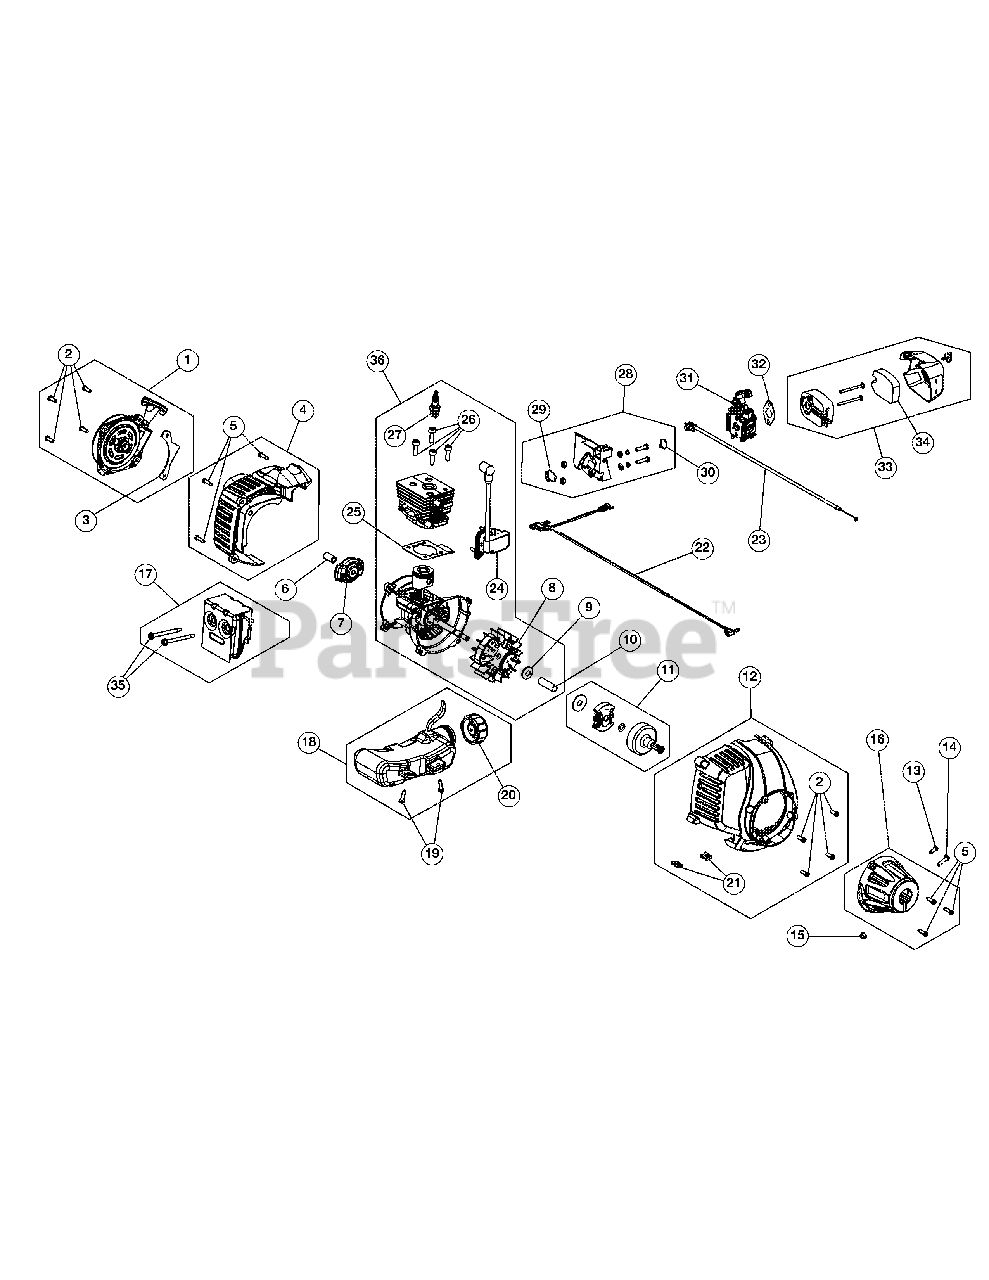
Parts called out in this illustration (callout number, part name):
1	Rear Cover Assembly (Incl. 2 & 3)
2	Starter Screw
3	Starter Assembly Guard (Incl. 2)
4	Rear Engine Cover Assembly (Incl. 5)
5	Cover Screw
6	Adapter
7	Pawl Assembly
8	Flywheel Assembly
9	Washer
10	Spacer
11	Clutch Assembly
12	Front Engine Cover Assembly (Incl. 2 & 21)
13	Anti-Rotation Screw
14	Clamp Screw
15	Clamp Nut
16	Clutch Cover Assembly (Incl. 5)
17	Muffler Assembly (Incl. 35)
18	Fuel Tank Assembly (Incl. 19 & 20)
19	Tank Screw
20	Fuel Cap
21	U-Shaped Nut
22	Lead Wires
23	Throttle Cable
24	Module Assembly
25	Cylinder Gasket
26	Cylinder Bolt
27	Spark Plug
28	Insulator Assembly (Incl. 29 & 30)
29	Insulator O-Ring
30	Carburetor O-Ring
31	Carburetor
32	Carburetor Gasket
33	Air Cleaner Assembly (Incl. 34)
34	Air Cleaner Filter
35	Muffler Screws
36	Short Block Assembly
